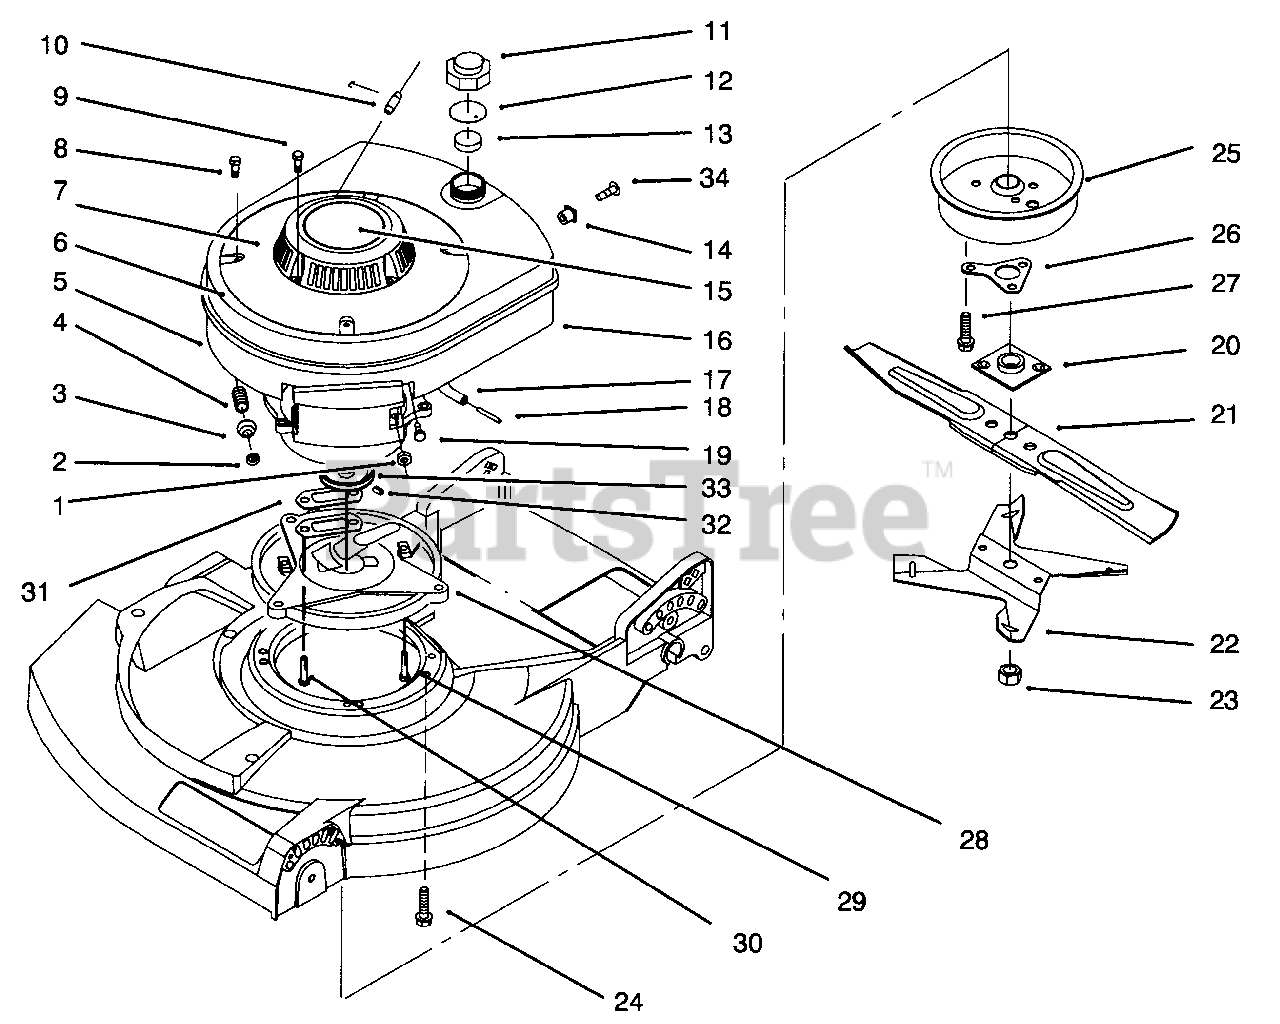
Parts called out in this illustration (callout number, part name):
1	Nut
2	Retainer
3	Actuator-Lever Brake
5	Shroud & Tank Assembly
6	Base-Starter
7	Starter Assembly
8	Screw-Self Tapping
10	Stop-Rope
11	Cap-Fuel
12	Gasket-Fuel Cap
13	Baffle Fuel Cap
14	Grommet
15	Decal-Recoil (Hand Push)
16	Engine Assembly
17	Line-Fuel
18	Screen-Fuel Line
20	Plate & Collar Assembly
21	Blade 21"
22	Fan-Mulching
23	Nut-Blade
24	Screw-Engine
25	Muffler Cover Assembly
26	Support-Crankshaft
28	Plate-Muffler
31	Gasket-Muffler
32	Screw-Set
34	Screw-Self Tapping
